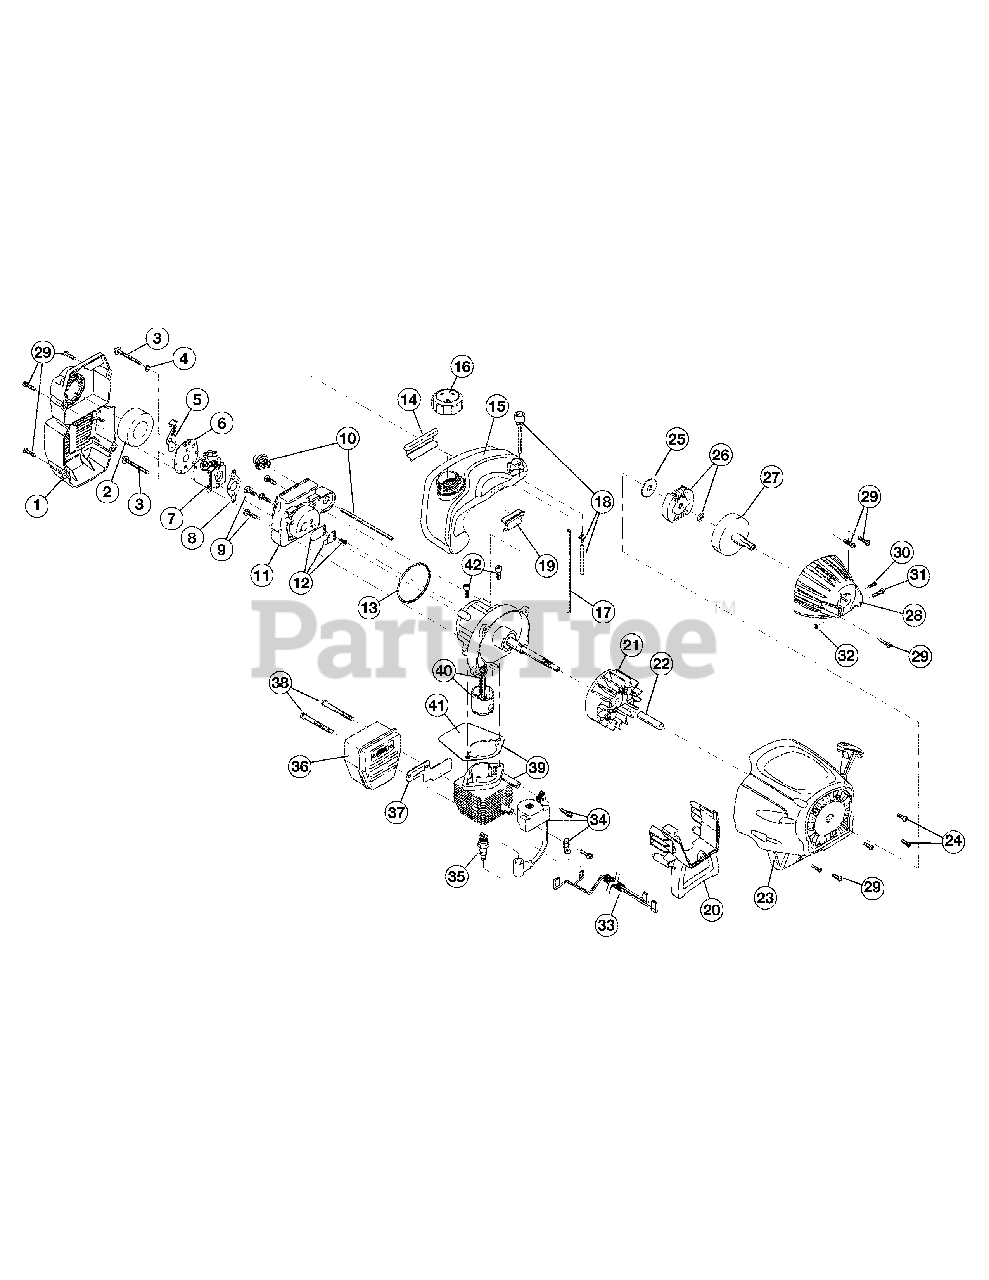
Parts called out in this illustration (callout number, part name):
1	Air Cleaner Cover Assembly
2	Air Cleaner Filter
3	Carburetor Mounting Screw Assembly
4	Wavey Washer
5	Choke Lever Assembly
6	Choke Plate Assembly
7	Carburetor Assembly
8	Carburetor Gasket
9	Carb Mount Screw
10	Primer & Hose Assembly
11	Carb Mount Assembly
12	Reed Assembly
13	O-Ring
14	Rear Mounting Pad
15	Fuel Tank Assembly
16	Fuel Cap Assembly
17	Fuel Return Line
18	Fuel Line Assembly
19	Front Mounting Pad
20	Shroud Extension & Stand
21	Flywheel Assembly
23	Starter Housing Assembly
24	Housing Screw
25	Clutch Washer
26	Clutch Rotor Assembly
27	Clutch Drum Assembly
28	Clutch Cover Assembly
29	Cover Screw
30	Anti-Rotation Screw
31	Clamping Screw
32	Clamping Nut
33	Wire Leads and Sleeve
34	Module Assembly
36	Muffler Assembly
37	Exhaust Gasket
38	Muffler Mounting Bolts
39	Cylinder Assembly
40	Piston and Rod Assembly
41	Cylinder Gasket
42	Cylinder Bolt
